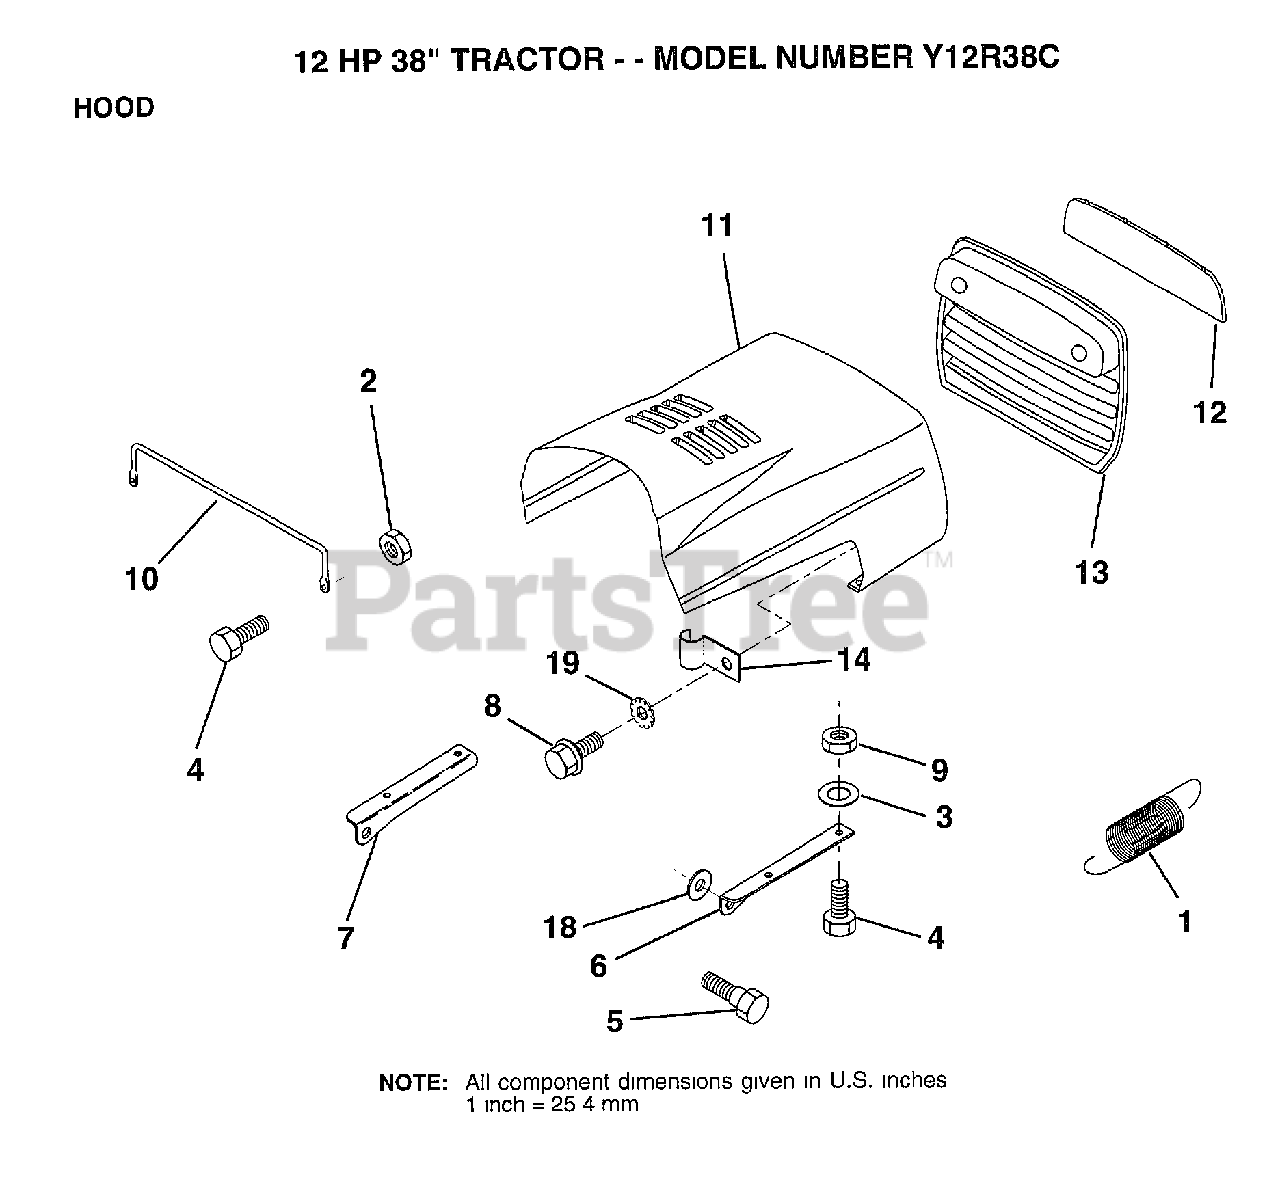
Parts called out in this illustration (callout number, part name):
1	EXT SPRING
2	NUT
3	WASHER
5	BOLT.SHLD.5/16-18
6	BRKT HOOD RH
7	BRKT HOOD LH
8	SCREW SLTD HXHD
9	NUT
10	"BRACE,HOOD"
11	HOOD
12	LENS
13	GRILL
14	CLIP T
18	WASHER
19	LOCKWASHER GT
23	LATCH.HOOD.LR
